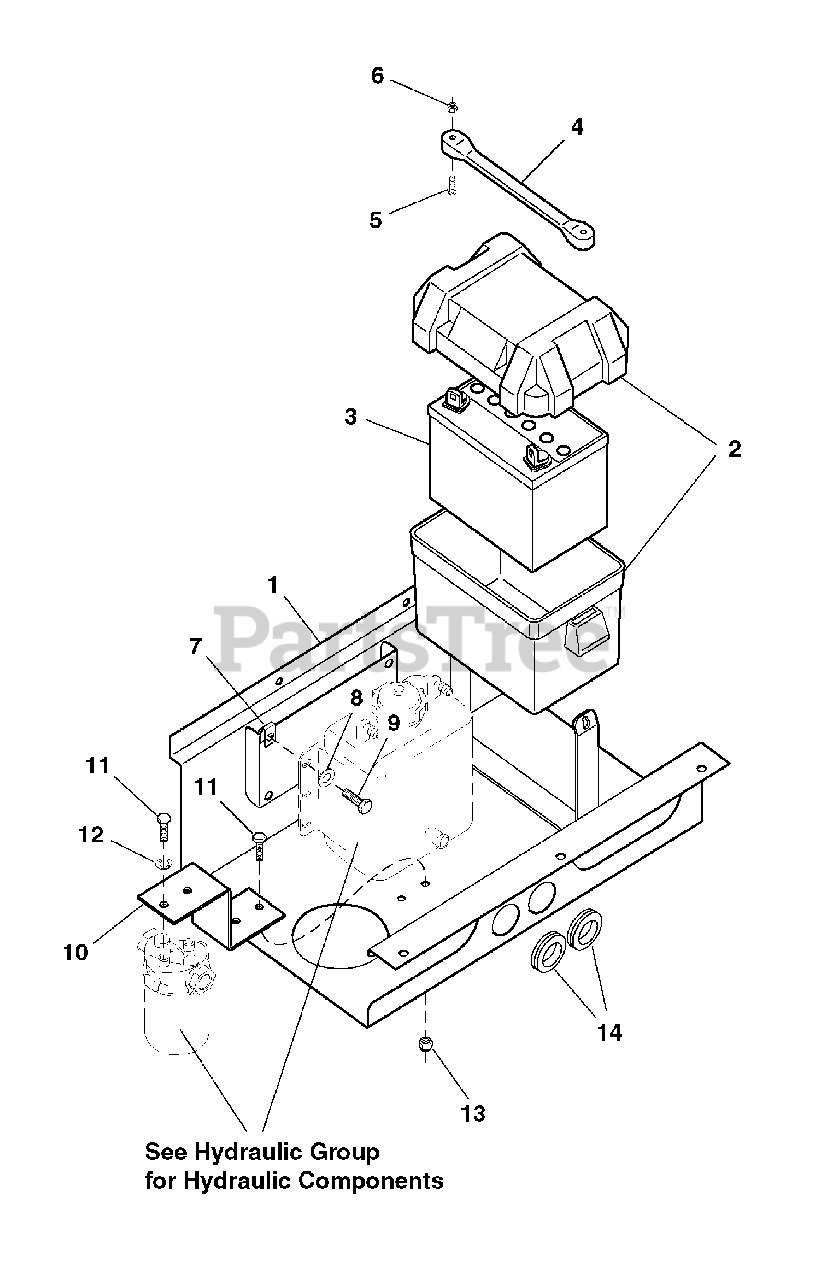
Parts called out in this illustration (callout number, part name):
1	BATTERY & RESERVOIR PAN
2	BATTERY BOX w/ Cover
3	BATTERY (shipped dry)
4	RUBBER STRAP
5	SCREW, Phillips, #10-24 x 1
6	NUT, Hex, Nylon Lock, #10-24
7	BODY CLIP, 5/16-18
8	WASHER, 5/16
9	CAPSCREW, Hex Hd, 5/16-18 x 1
10	MOUNT, Filter Head
11	CAPSCREW, Hex Hd, 1/4-20 x 3/4
12	WASHER, Lock, 1/4
13	NUT, Hex, Nylon Lock, 1/4-20
14	GROMMET, 1-1/4
